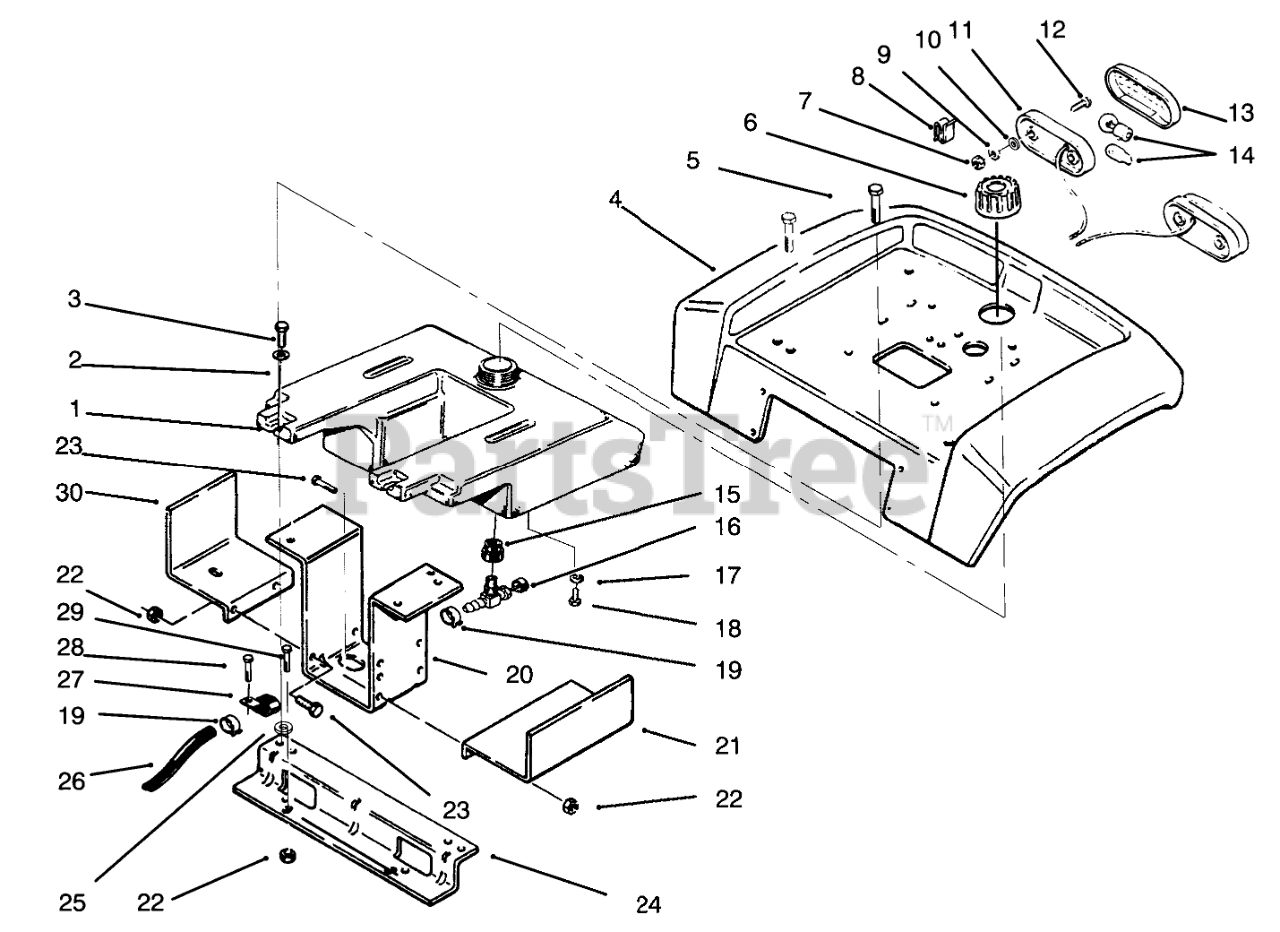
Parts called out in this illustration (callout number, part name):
1	TANK-FUEL
2	WASHER-FLAT
3	Bolt
4	Fender
5	SCREW
6	GAS CAP ASM
7	NUT-LOCK, NI
8	SPEED CLIP
9	WASHER-FLAT
10	WASHER-LOCK, INT
11	BASE-TAIL LIGHT
12	Screw
13	LENS-TAIL LIGHT
14	Bulb
15	BUSHING
16	VALVE-FUEL
17	WASHER-LOCK
18	SCREW-HH
19	CLAMP-HOSE
20	Bracket-Fender
21	Fuel Tank Support LH
22	NUT-LOCK, NI
23	SCREW-HH
24	BRACKET-FENDER B
25	WASHER-PLAIN
26	Line-Fuel 62"
27	CLIP
28	SCREW-HH, LOCK
29	SCREW-HH
30	Support-FueITank RH
